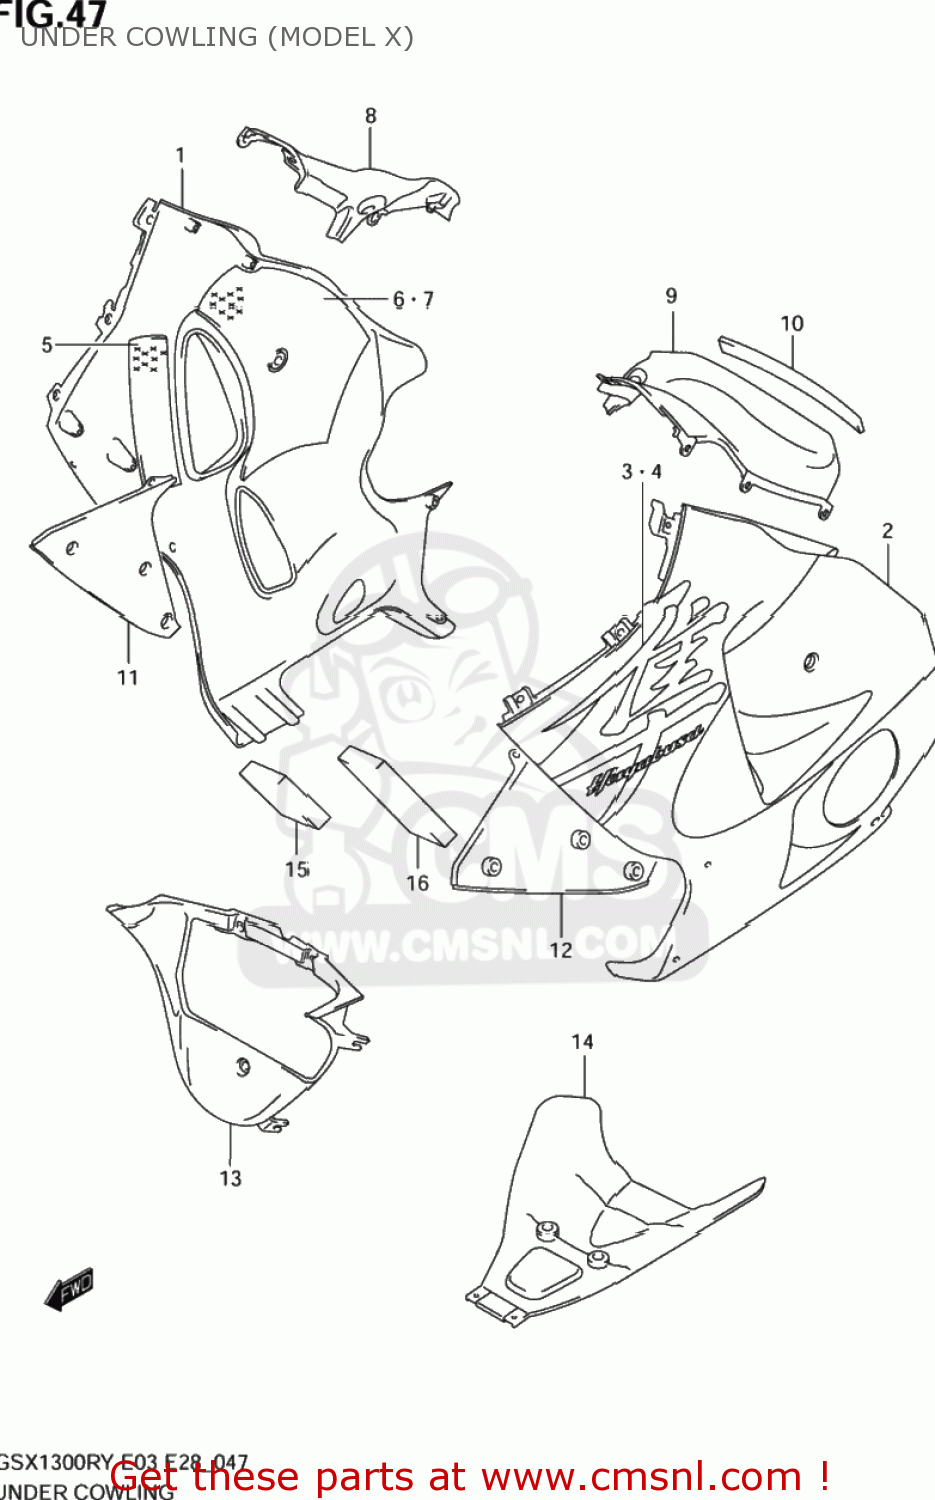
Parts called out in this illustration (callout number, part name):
1	COWLING ASSEMBLY,UNDER,RIGHT
2	COWLING,UNDER,LEFT
3	EMBLEM,COWLING UNDER,R
4	EMBLEM,COWLING UNDER,L
5	CUSHION,UNDER COWLING
6	CUSHION,UNDER COWLING,RIGHT
7	CUSHION,UNDER COWLING,L
8	PANEL,SIDE,R
9	PANEL,SIDE,L
10	MOLDING,SIDE PANEL
11	COWLING,UNDER INNER,R
12	COWLING,UNDER INNER,L
13	COWLING,UNDER,CENTER
14	COWLING,UNDER RR
15	CUSHION,UNDER COWLING,RIGHT
16	CUSHION,UNDER COWLING,L
